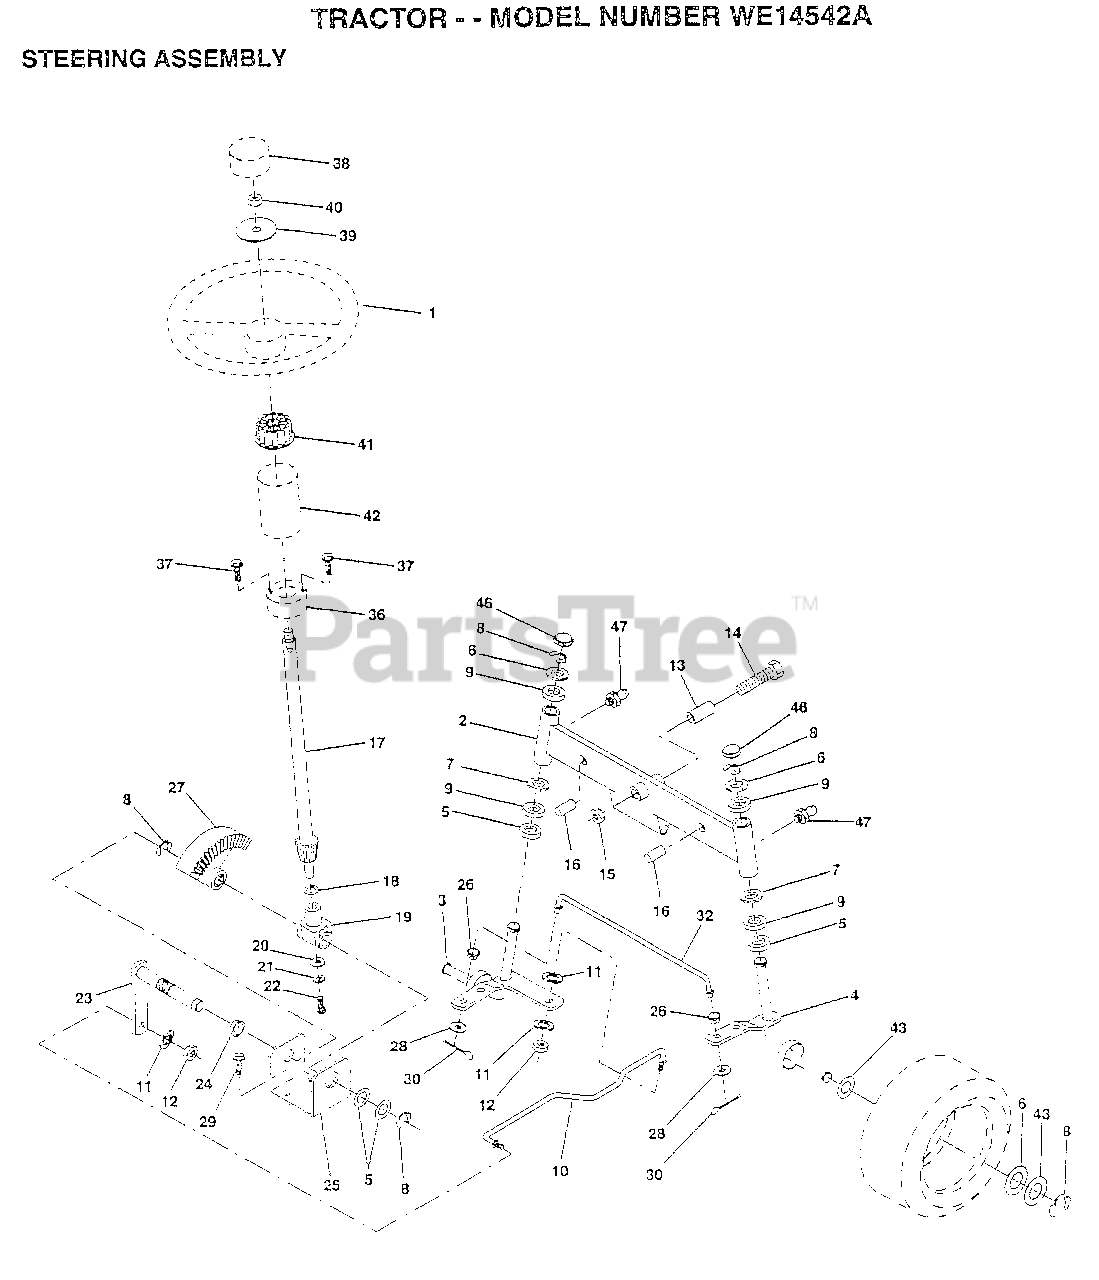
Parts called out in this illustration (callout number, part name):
2	AXLE ASM FRONT
3	SPINDLE LH
4	SPINDLE RH
5	WASHER .T
6	WASHER
7	WASHER
8	RING
9	COL. SRTG. BEAR.
11	LOCKWASHER
13	BEARING
14	BOLT HEX 5/8-11
15	"NUT-LOC,FLANGE LT"
16	AXLE PIN
17	SHAFT ASM
18	THRUST WASHER
19	SUPPORT.SHAFT
21	LOCKWASHER
22	"SCREW,SPECIAL"
24	NYLINER T
25	"BRKT,STEERING"
26	BUSHING.DRAGLINK
27	GEAR SECTOR
28	WASHER
29	SCREW
30	COTTER PIN
32	TIE ROD
38	ST WHL INSERT CAP
39	WASHER T
40	GRIPCO NUT
41	ADAPTER-WHEEL LT
42	"TUBE, STR SHAFT"
43	WASHER
46	CAP
47	ZERK M
